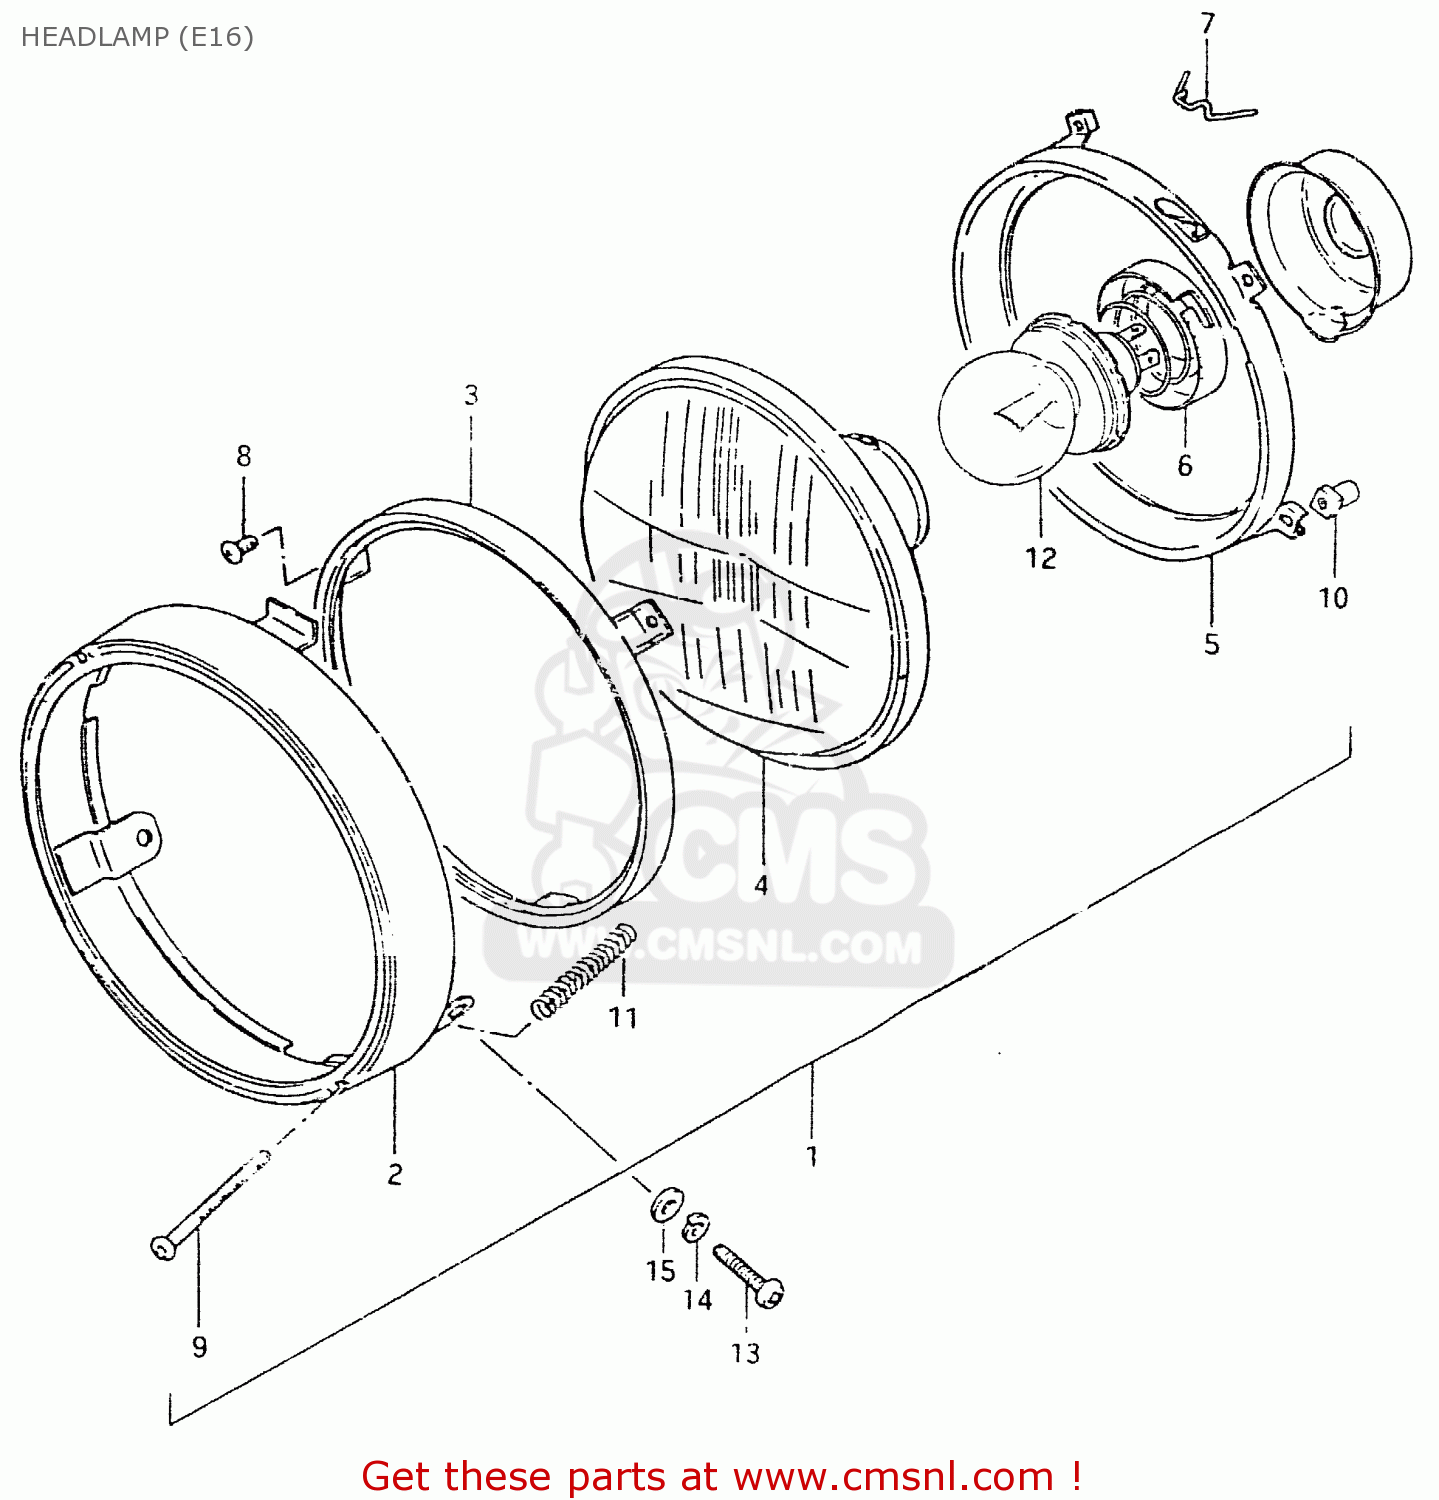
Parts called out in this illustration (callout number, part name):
1	HEADLAMP ASSY
2	RIM
3	RETAINER,HEADLAMP
4	UNIT
5	RING, MOUNTING
6	SETTER,BULB
7	SPRING,HEADLAMP UNIT
8	SCREW
9	SCREW,HEADLAMP ADJUST
10	NUT,HEADLAMP ADJUSTER
11	SPRING,ADJUSTING
12	BULB (6V,45/40W)
13	SCREW
14	LOCK WASHER
15	WASHER
